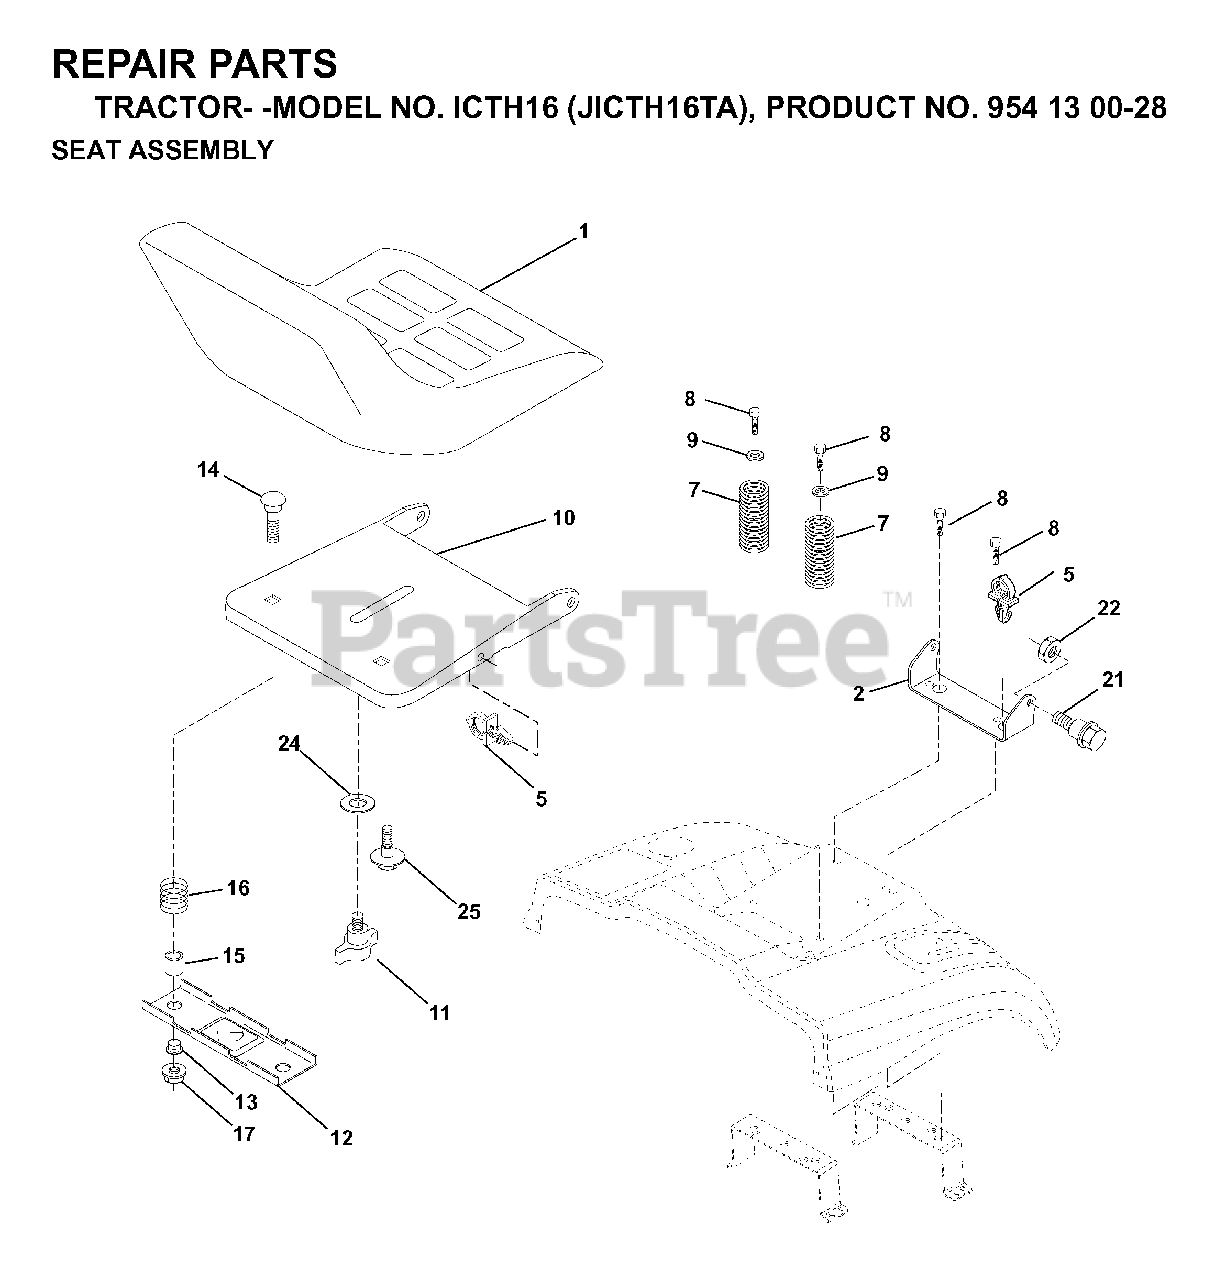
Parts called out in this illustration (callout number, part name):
2	SEAT PIVOT BRKT
5	PUSH CLIP
7	SPRING COMPRESSION
8	SCREW GTV
9	WASHER
10	PAN, SEAT
11	KNOB.SEAT.ADJ.WINGNUT
12	BRKT SWITCH
14	BOLT.ROUND.HEAD.SQUARE.NECK
15	SPACER SPLIT 28X.96
17	NUT T
21	BOLT SHOULDER 5/16-18
22	NUT.71038.31-18.HEX.NYLOCK
25	BOLT,SHOULD
